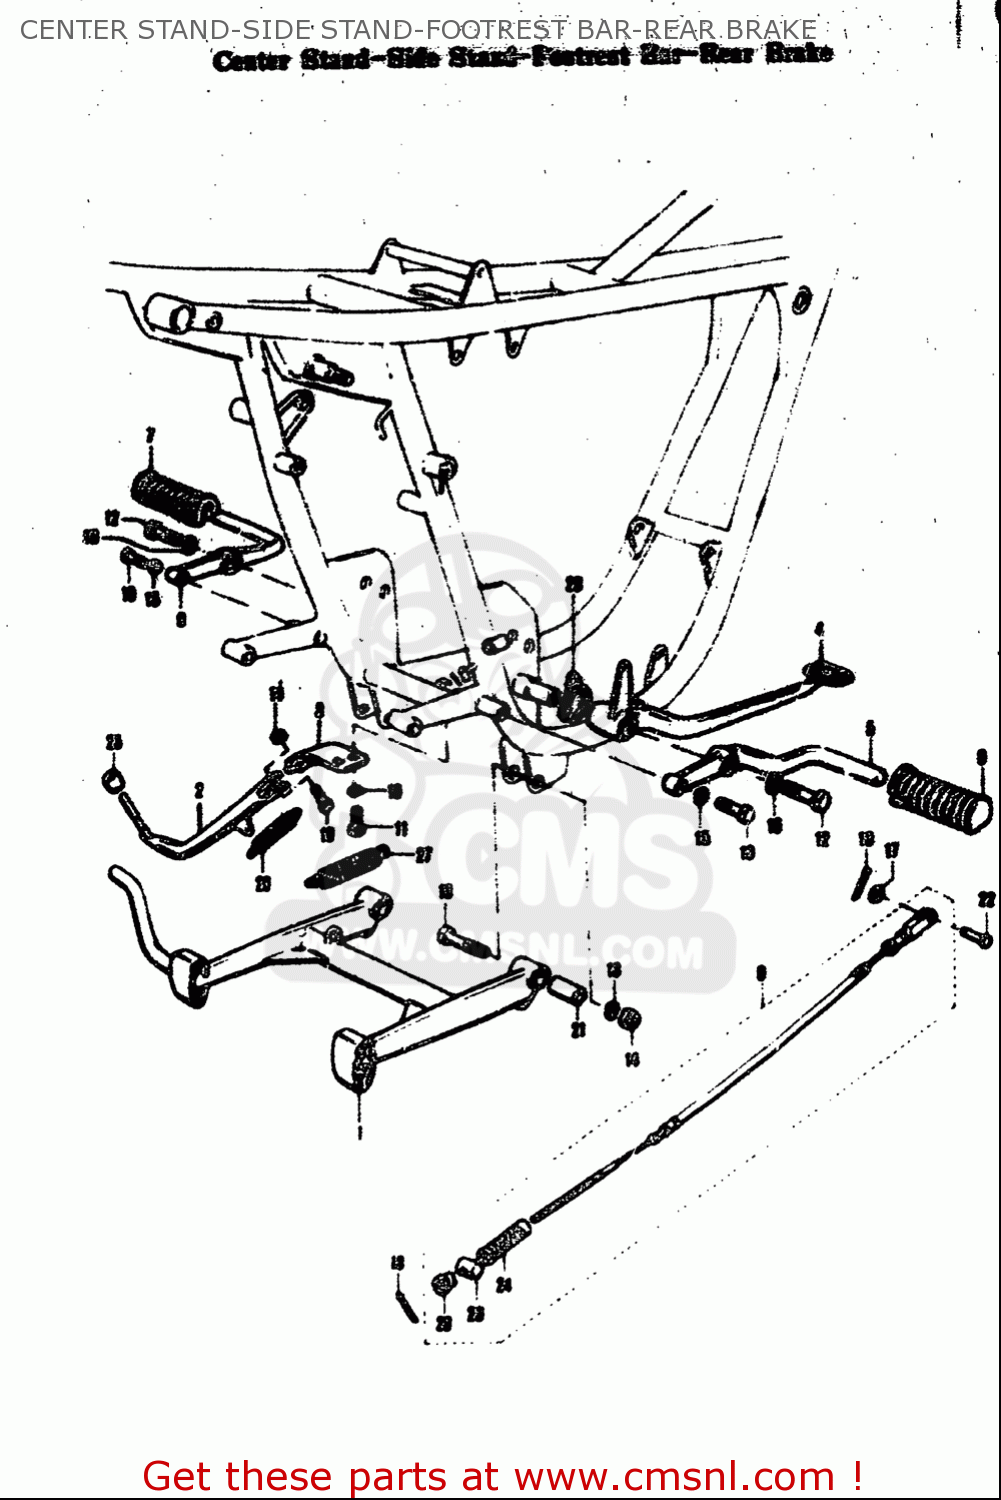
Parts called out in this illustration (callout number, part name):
2	STAND,PROP
3	BRACKET,SIDE STAND
7	RUBBER,FR FOOTREST
8	RUBBER,FR FOOTREST,R
9	CABLE ASSY,RR BRAKE
11	BOLT
12	BOLT
14	NUT
15	WASHER,LOCK
16	WASHER,LOCK
17	WASHER
18	BOLT(10X48)
19	BOLT(10X27)
20	NUT
21	SPACER(10.5X16X30)
22	PIN(L:17.5)
23	PIN(13X18)
24	SEAL,DUST
25	CUSHION
26	SPRING
27	SPRING
28	SPRING
